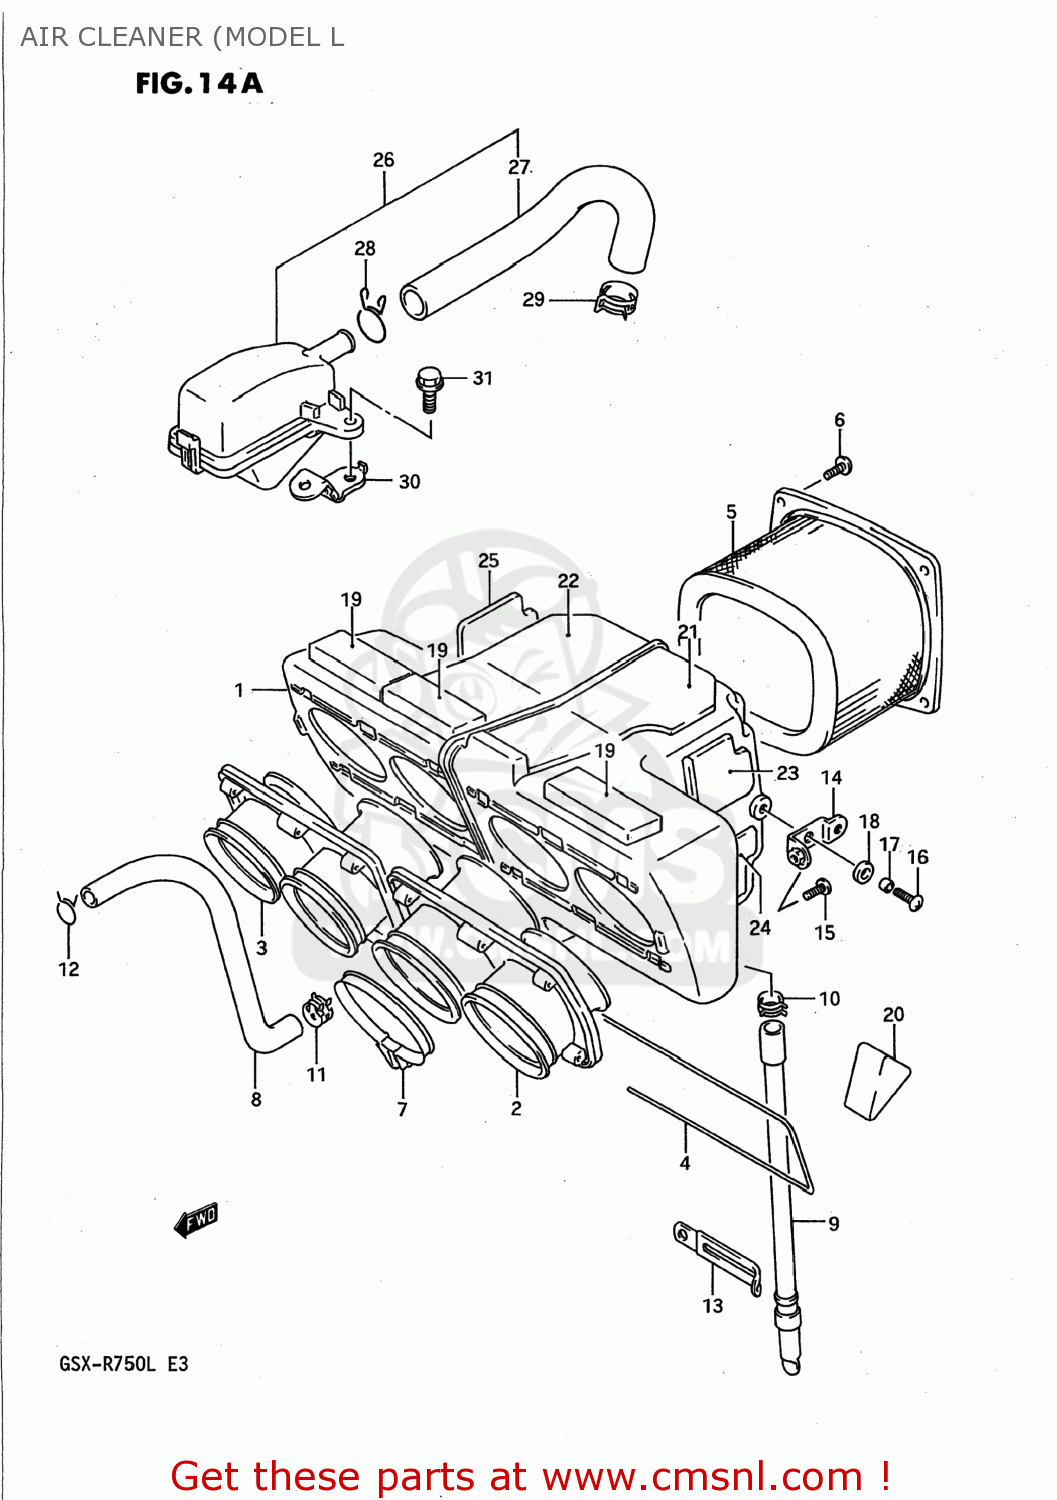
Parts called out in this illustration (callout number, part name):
1	CASE,AIR CLEANER
2	TUBE,OUTLET,L
3	TUBE,OUTLET,R
4	SHAFT,OUTLET TUBE
5	FILTER ASSY,AIR CLEANER
6	SCREW
7	CLAMP
8	TUBE,BREATHER
9	DRAIN TUBE
10	CLIP
11	CLIP
12	CLIP
13	CLAMP
14	BRACKET,AIR CLEANER CASE
15	SCREW
16	SCREW(6X18)
17	SPACER
18	WASHER
19	CUSHION,AIR CLEANER CASE
20	CUSHION,AIR VENT HOSE
21	SHEET,AIR CLEANER NO.1
22	SHEET,AIR CLEANER NO.2
23	SHEET,AIR CLEANER NO.3
24	SHEET,AIR CLEANER NO.4
25	SHEET,AIR CLEANER NO.5
26	CLEANER ASSEMBLY,AIR
27	TUBE,2ND AIR CLEANER
28	CLIP
29	CLAMP
30	BRACKET,2ND AIR CLEANER
31	BOLT
